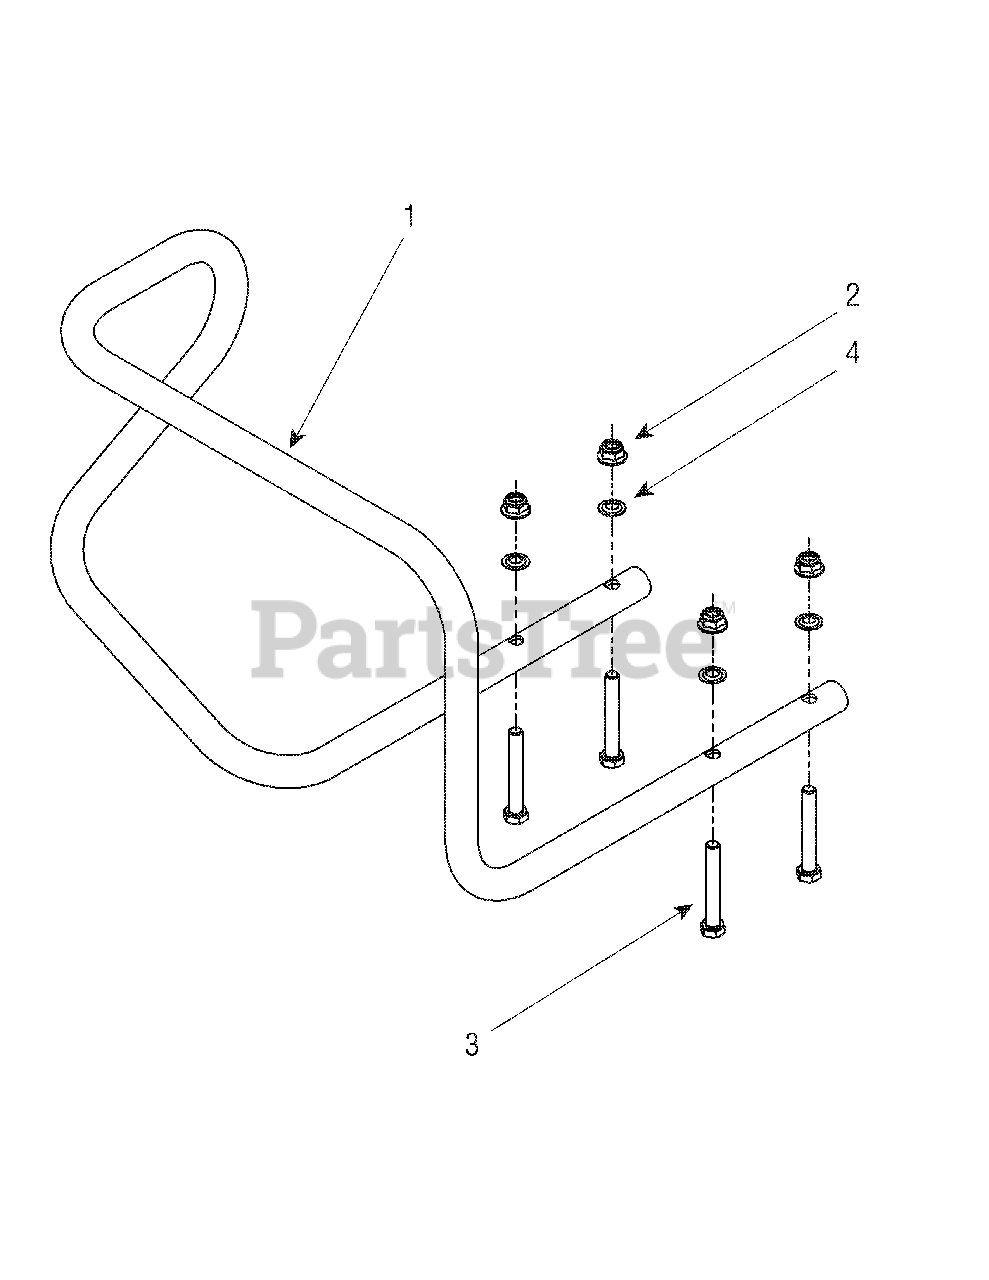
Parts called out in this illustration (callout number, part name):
2	Lock Nut - Hex, Nylon, 5/16-18
3	Screw - hex hd., 5/16-18 x 2-1/4
4	Lockwasher - 5/16
5	Lock Nut - Hex, Nylon, 5/16-18
